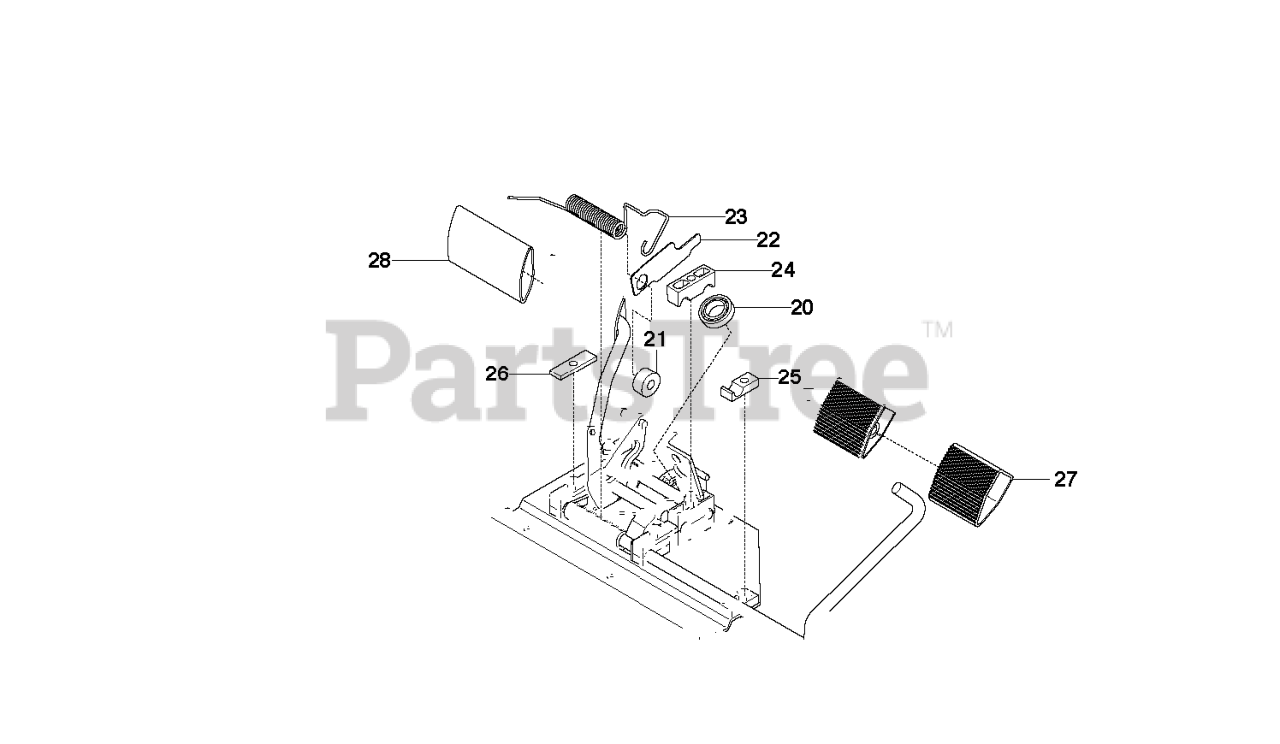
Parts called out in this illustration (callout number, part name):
20	BALL BEARING 6002-2RS1
21	ROLLER
22	PLATE
23	SPRING
24	PEDAL SHAFT CLAMP
25	SUPPORT
26	PLATE
27	PEDAL RUBBER
28	PEDAL RUBBER, SF
